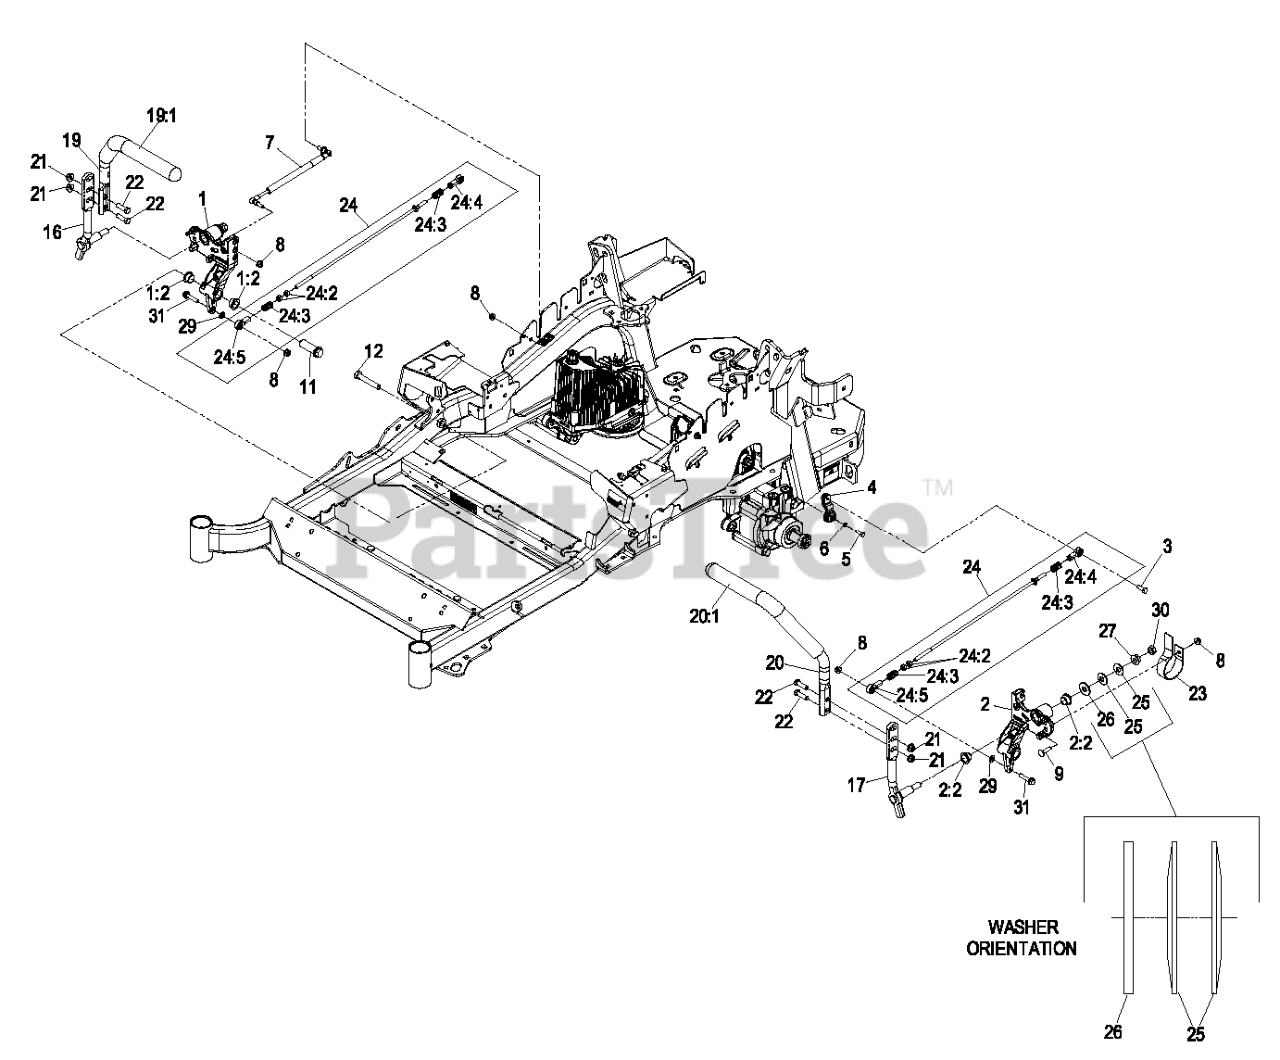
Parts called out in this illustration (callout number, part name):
1	RH MOTION CONTROL AND BUSHING ASM
1:2	BUSHING-FLANGE
2	LH MOTION CONTROL AND BUSHING ASM
2:2	BUSHING-FLANGE
3	SCREW-HH, THREAD LOCKING
4	ARM-CONTROL, PUMP
5	SCREW-HH
6	WASHER-SPRING
7	DAMPER-CONTROL, MOTION
8	NUT-HF, NI
9	BOLT-CARR
11	HUB-THREADED
12	SCREW-HH
16	LEVER-CONTROL MOTION, RH
17	LEVER-CONTROL MOTION, LH
19	RH STEERING HANDLE ASM
19:1	GRIP-LEVER, CONTROL
20	LH STEERING HANDLE ASM
20:1	GRIP-LEVER, CONTROL
21	NUT-HF, NI
22	SCREW-HH
23	SPRING-LEAF
24	PUMP LINKAGE REAR ASM
24:2	NUT-HEX
24:3	SPRING-COMPRESSION
24:4	BALLJOINT-LH
24:5	BALLJOINT-RH
25	WASHER-SPRING
26	WASHER-FLAT
29	WASHER-PLAIN
30	NUT-JAM
31	SCREW-HHF
